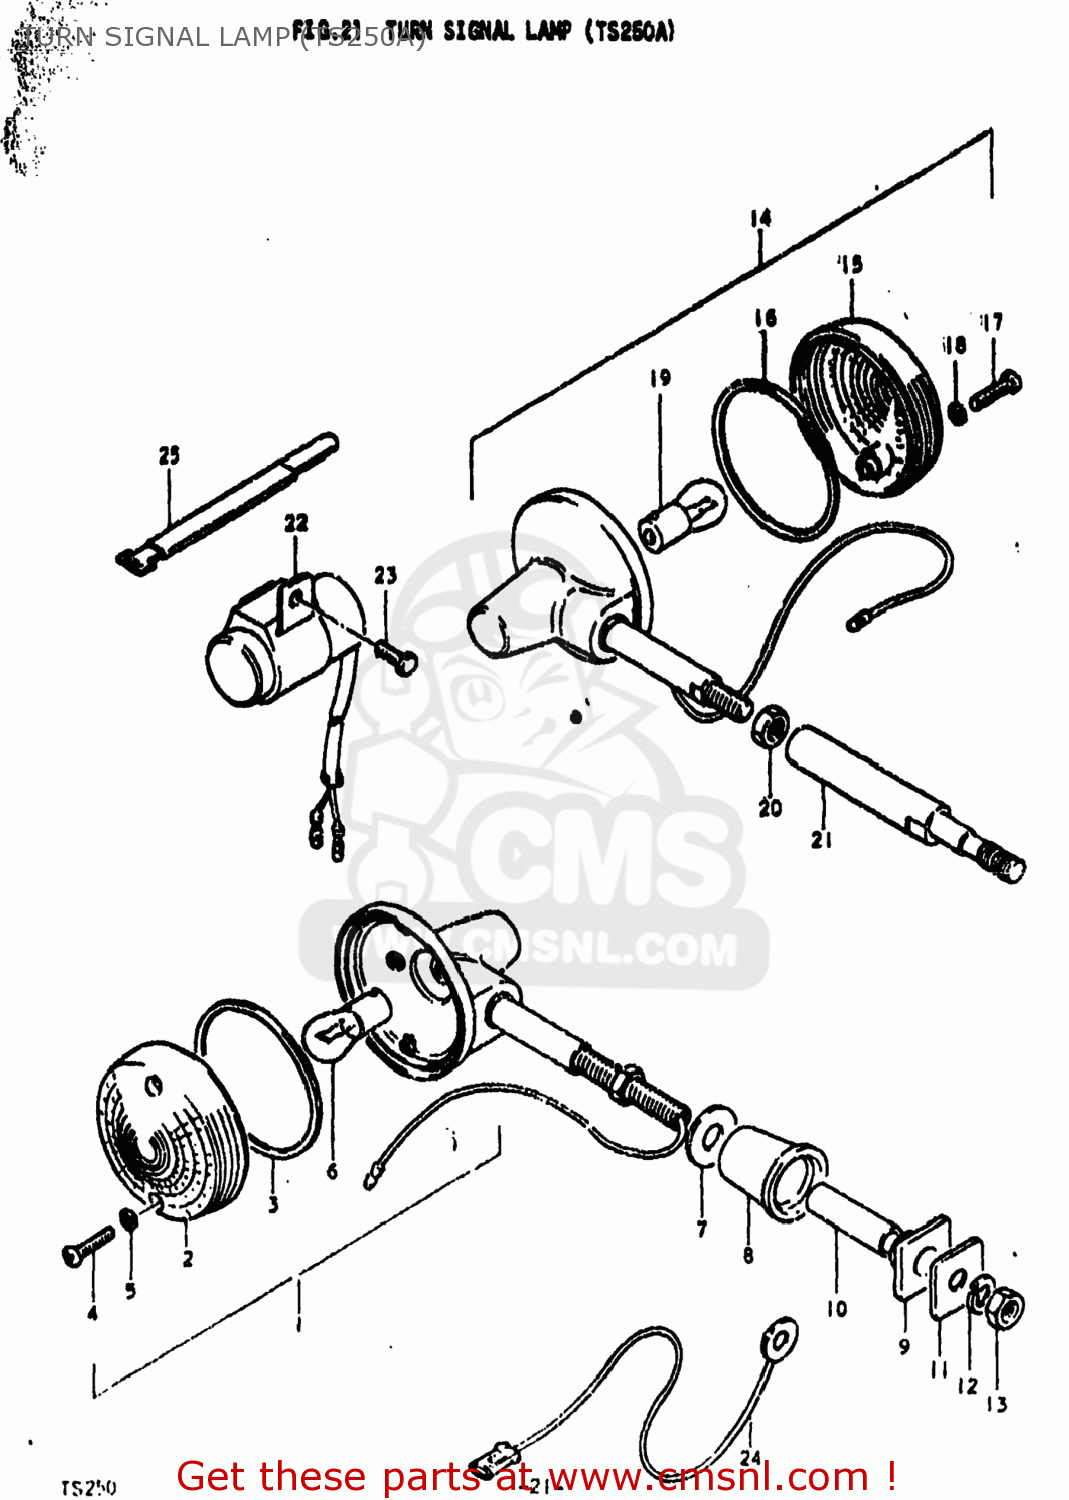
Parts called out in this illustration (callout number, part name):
1	LAMP ASSEMBLY,FRONT TURN SIGNAL
2	LENS
3	GASKET (NAS)
4	SCREW
5	GASKET (NAS)
6	BULB(6V17W,STANLEY,A4513A)
7	WASHER (10.5X30X2.3)
8	CUSHION
9	CUSHION,FRONT TURNSIGNAL
10	SPACER, TURN SIGNAL
11	PLATE, TURN SIGNAL
12	LOCK WASHER
13	NUT
14	LAMP ASSEMBLY,REAR TURN SIGNAL
15	LENS
16	GASKET (NAS)
17	SCREW
18	GASKET (NAS)
19	BULB(6V17W,STANLEY,A4513A)
20	NUT
21	STAY,TURN SIGNAL,REAR
22	RELAY,TURN SIGNAL
23	BOLT
24	WIRE
25	CLAMP
